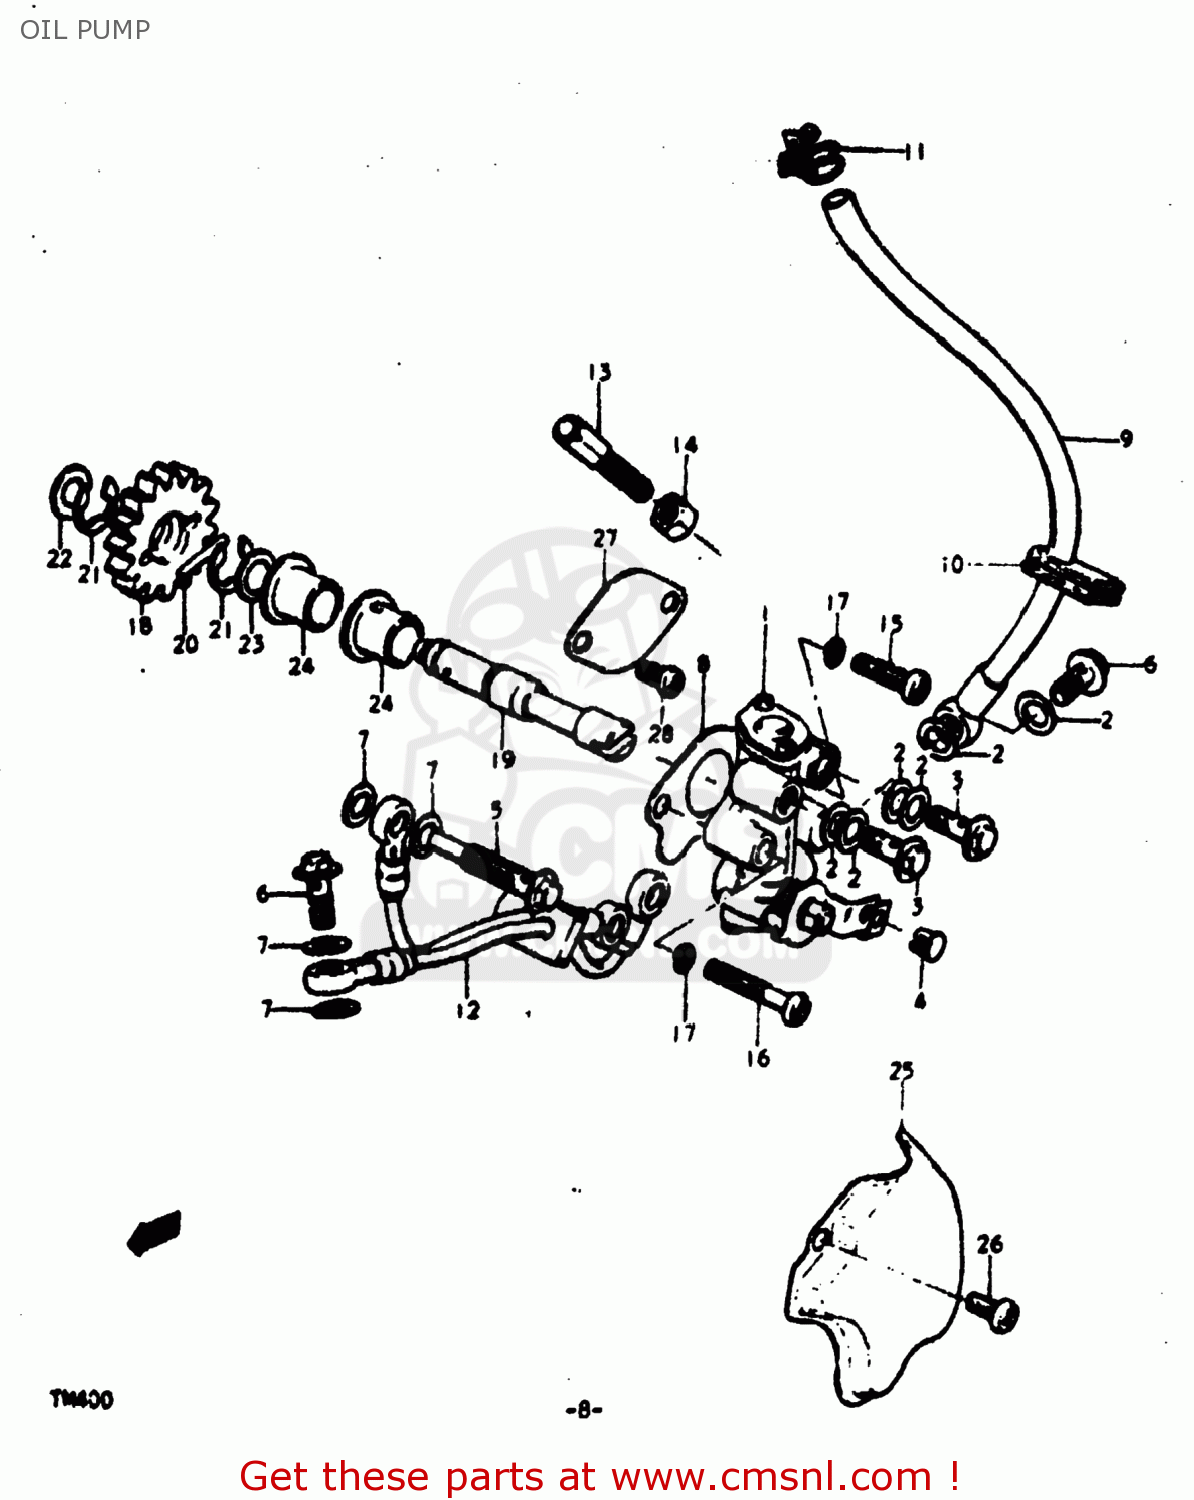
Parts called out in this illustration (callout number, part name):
1	PUMP ASSEMBLY,OIL
2	GASKET (NAS)
3	UNION BOLT
4	TERMINAL,CABLE
5	UNION
6	UNION BOLT
7	GASKET
8	GASKET,OIL PUMP (MCA)
9	HOSE,OIL NO.1
10	GROMMET
11	CLAMP
12	HOSE,OIL NO.2
13	BOLT
14	NUT
15	SCREW
16	SCREW
17	LOCK WASHER
18	GEAR,OIL PUMP DRIVE
19	SHAFT,OIL PUMP IDLE GEAR
20	ROLLER(4X23.8)
21	E RING
22	WASHER
23	SHIM(10X16X1)
24	BUSHING
25	CAP
26	SCREW
27	CAP,OIL PUMP DRIVE SHAFT
28	Screw
